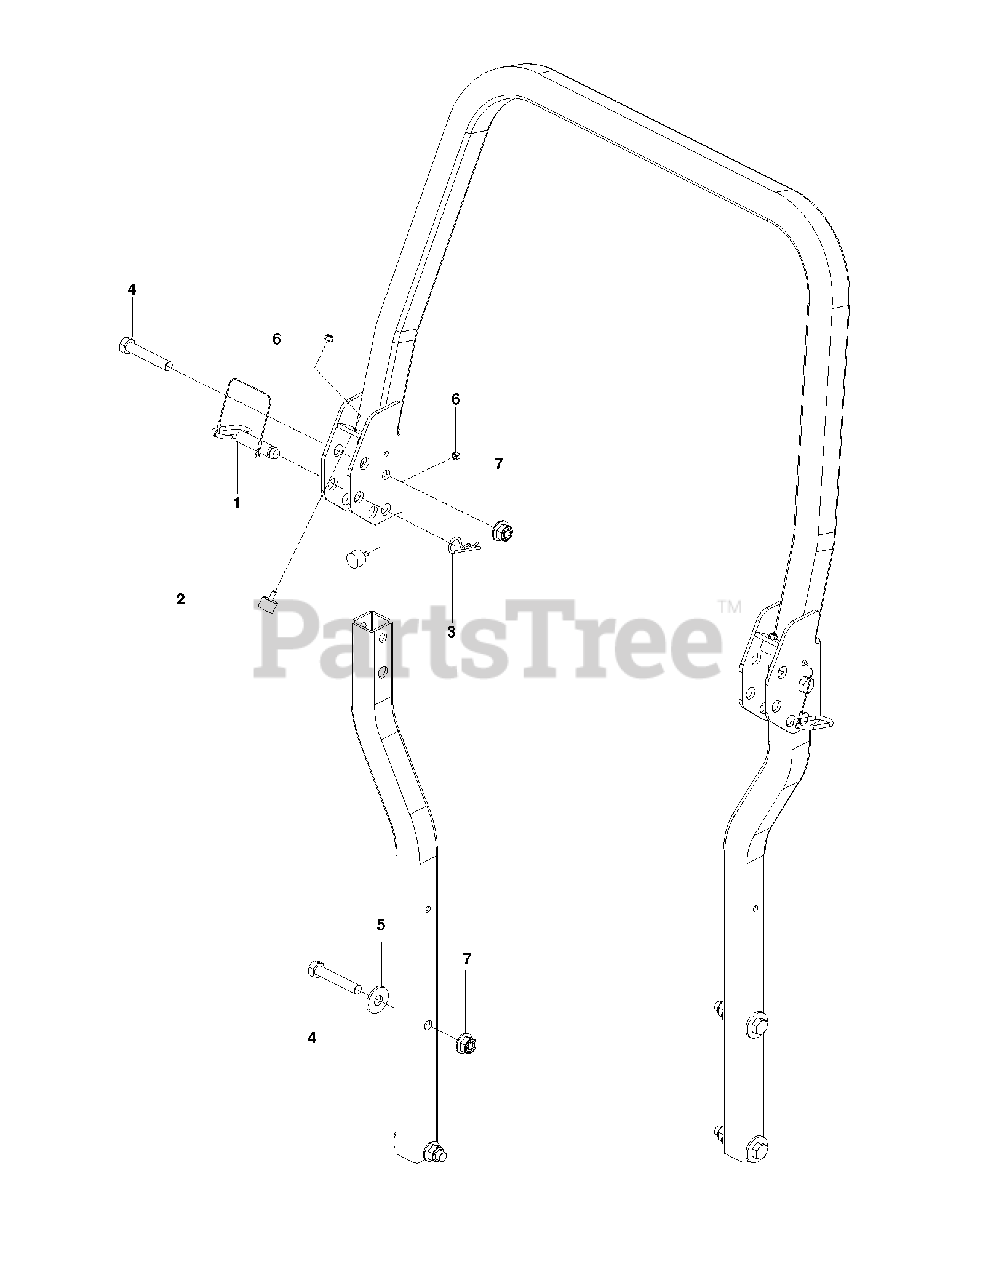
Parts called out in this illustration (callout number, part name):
2	BUMPER, MALE STUD, 1/4-20
3	PIN HAIR .148 X 2-15/16 #210
4	5/8-11 X 3-1/2 HHB GRADE 5
5	WASHER, 5/8 FLAT
6	RP_NUT 1/4-20 NYLOC
7	NUT 5/8-11 FLG NYLOC ZD
